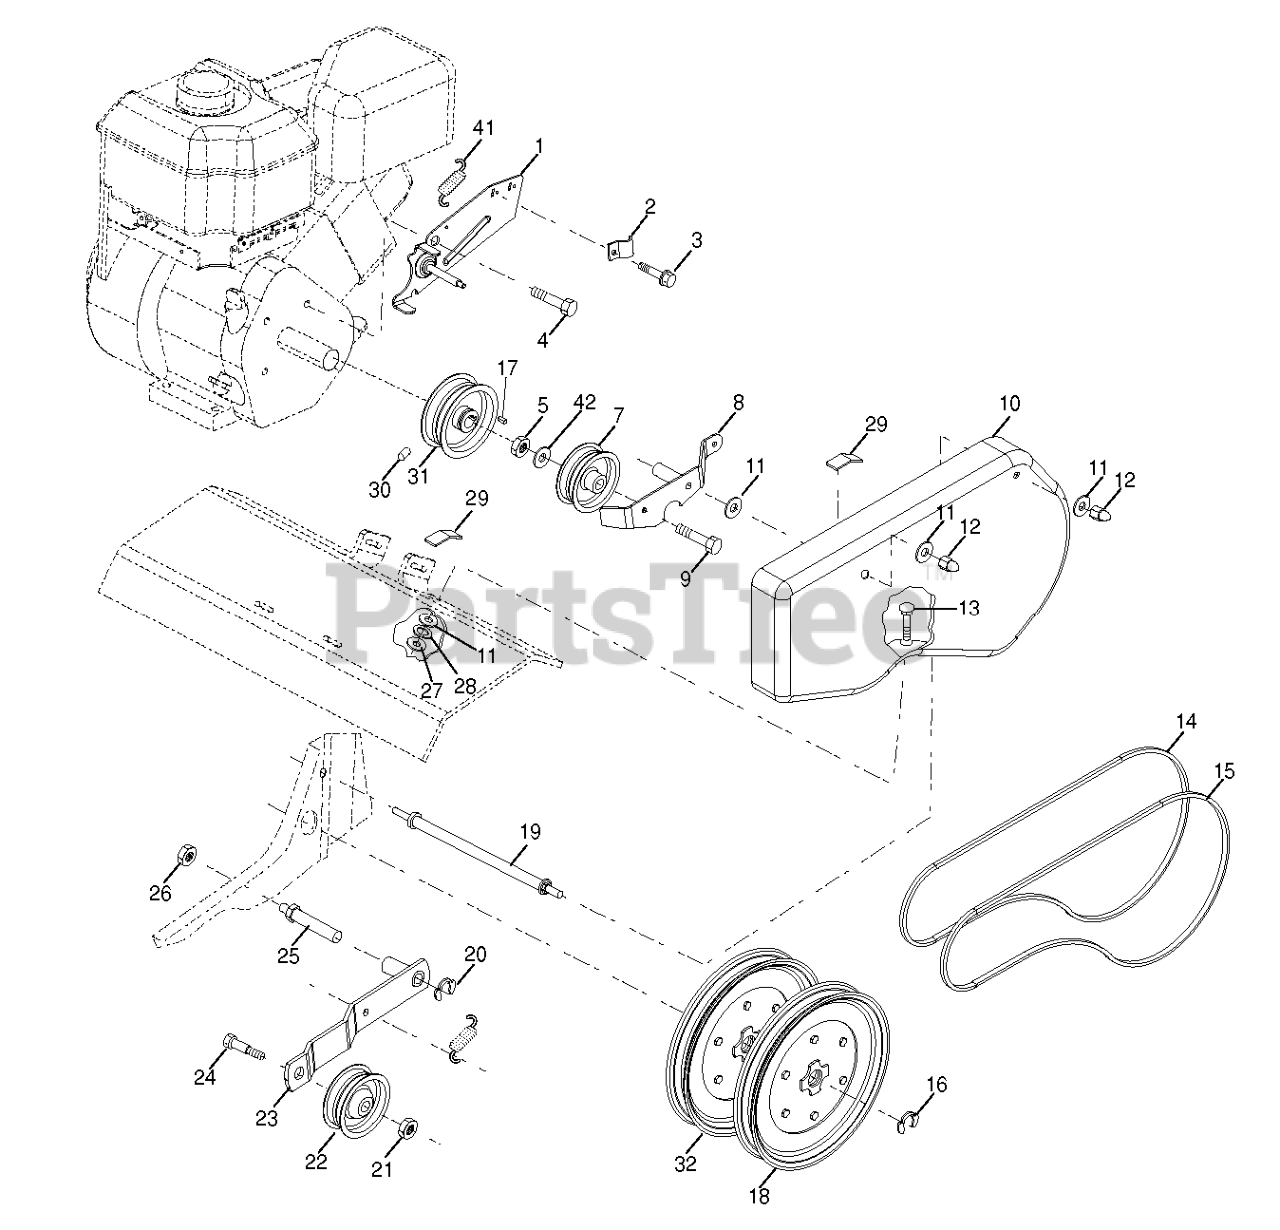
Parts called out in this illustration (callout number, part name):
1	BRACKET,BELTGUARD ASM
2	CLIP.PLATED
3	TAPPING SCREW
4	Bolt, Hex Head 1/2-20 x 3/4
5	NUT.LOCK.5/16-18
7	PULLEY FLAT IDLER
8	ARM.ASM.REV.IDLER.TILLER.BLACK
9	BOLT.FIN HEX 5/16-18UNC X2 1/4
10	GUARD.BELT.TILLER.ORANGE
12	CAP
13	BOLT
15	BELT.TILLER.DRIVE
16	RETAINING RING LT
17	KEY.SQ.187 X 1.125
18	SHEAVE,TRANS."D"
19	BOLT.BELT.GUARD
20	KLIP RING TI
21	NUT.LOCK.5/16-18
22	PULLEY.W/SPACER.2.25
23	ARM.ASM.IDLER.PNT
25	SHAFT.IDLER.TILLER
26	JAM NUT TI
27	NUT
28	LOCKWASHER
29	PAD IDLER TI
31	ENGINE.PULLEY.TILLER
32	SHEAVE.TRANS
41	SPRING.EXTENSION
